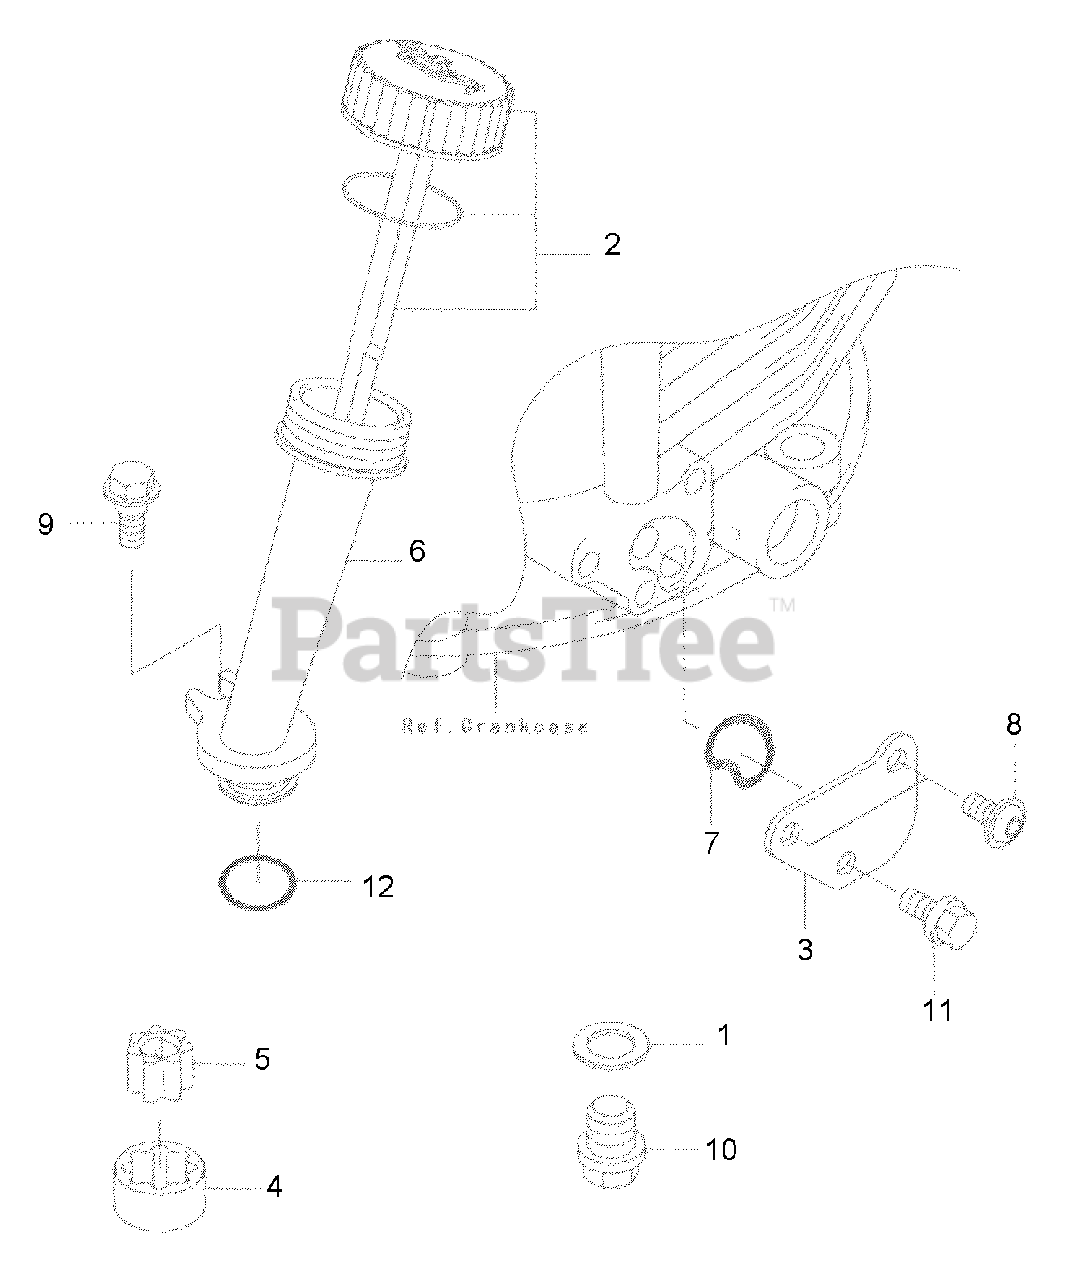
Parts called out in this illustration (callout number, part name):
1	Gasket, 12x19x1.27
2	Dipstick Cap Assy.
3	Oil Filter Cover
4	Oil Pump Rotor (Outer)
5	Oil Pump Rotor (Inner)
6	Filler Tube
8	Bolt, 6x12
11	Flanged Bolt
12	O-Ring, 16mm
